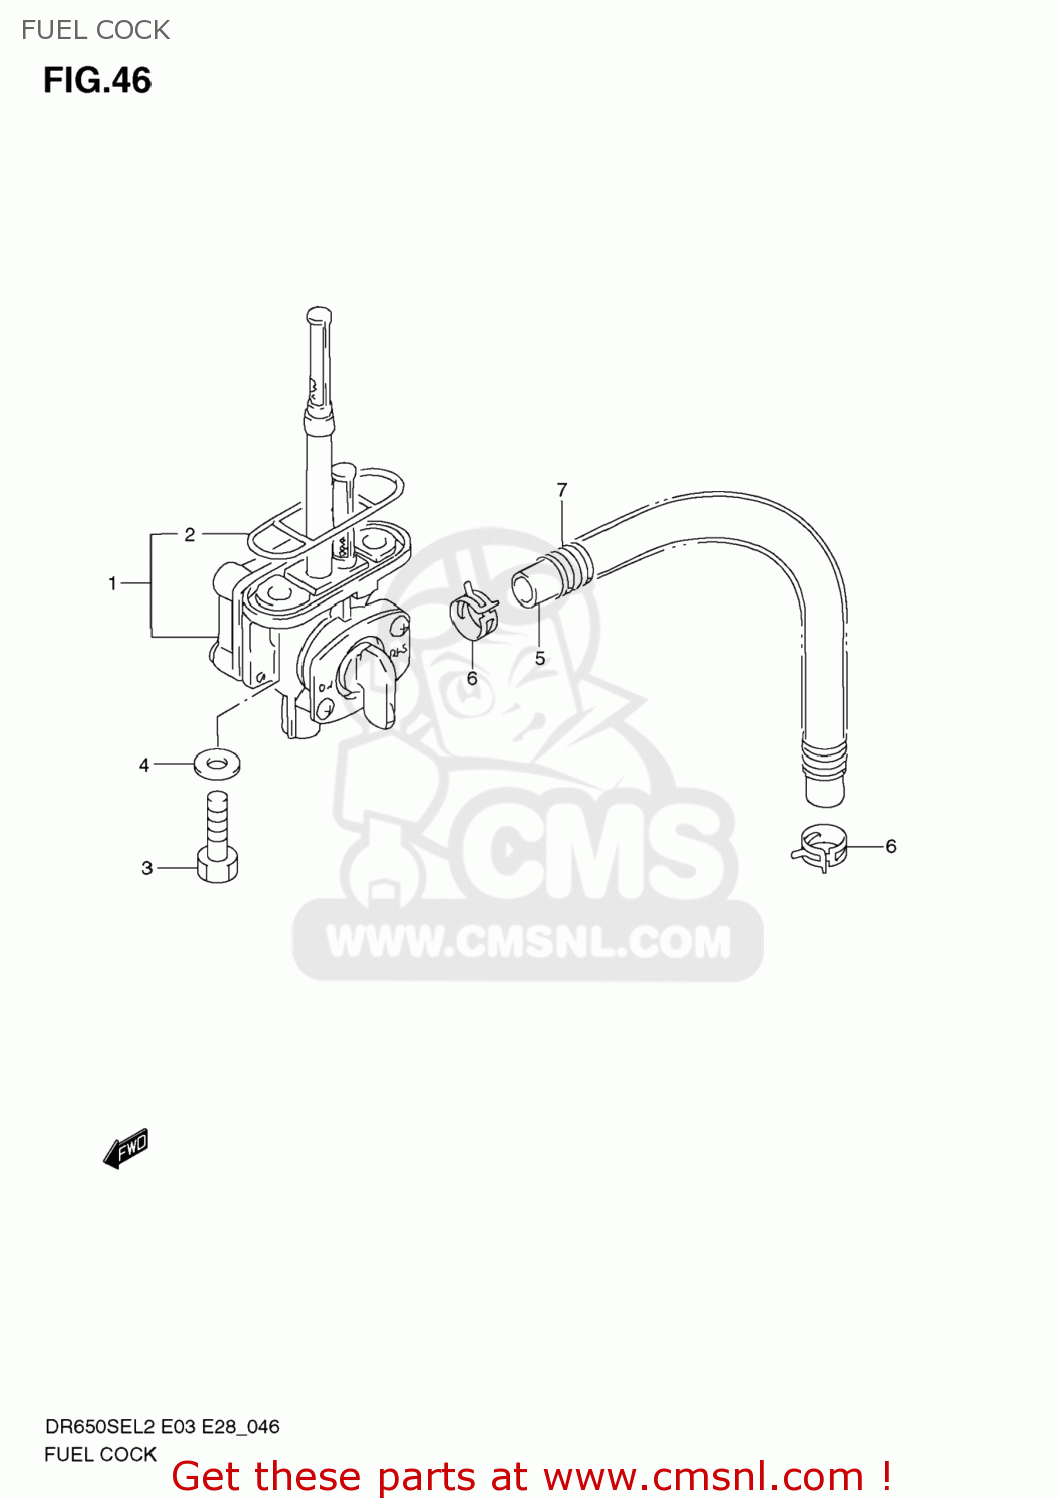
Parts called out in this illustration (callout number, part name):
1	COCK ASSY,FUEL
2	GASKET,JOINT (NAS)
3	BOLT(6X20)
4	GASKET(6.4X11.5X0.8) (NAS)
5	HOSE,FUEL
6	CLIP
7	SPRING
